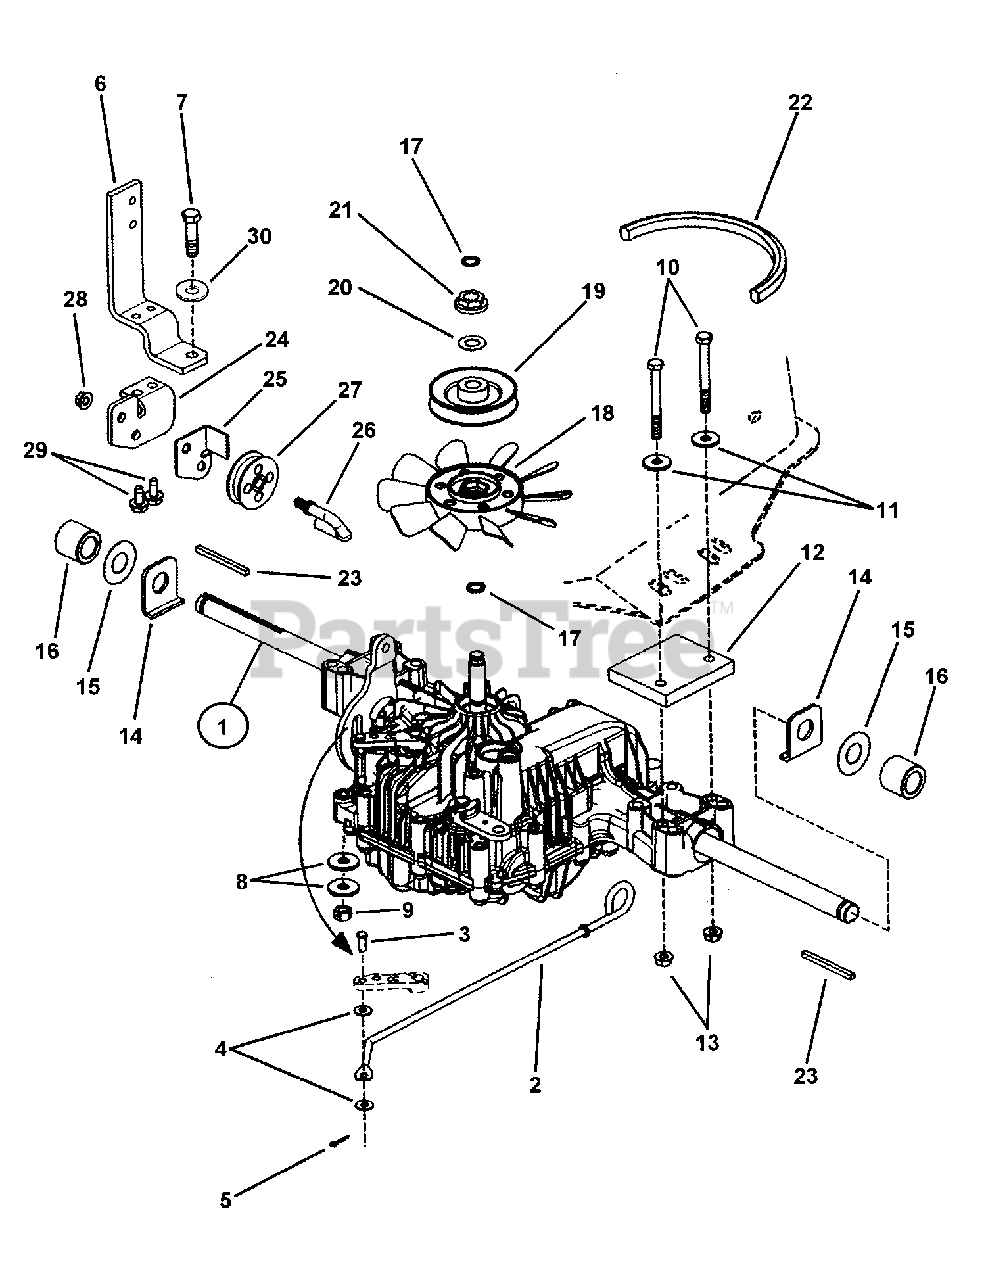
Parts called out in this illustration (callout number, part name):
1	ASSEMBLY, Transaxle-Tuff Torq, hand control K46 Hydro
2	ROD, Roll Release- K46
3	PIN, 1/4 x 5/8" Clevis
4	WASHER, 1/4 x 5/8 x 1/16" Flat
5	PIN, 3/32 x 1/2" Cotter
6	BRACKET, Torque/Spool- TTK46
7	SCREW, 5/16-18 x 2" Hex Head Cap, GR5
8	WASHER, 5/16 x 11/16 x 1/16" Flat, GR5
9	NUT, 5/16-18-3B Hex Nyloc
10	SCREW, 5/16-18 x 3" Hex Head Cap, GR5
11	WASHER, .34 x 1.0 x .09 Flat
12	SPACER, Hydro Axle- Steel- K46
13	NUT, 5/16-18 Hex Flange Lock, GR5
14	WASHER, Axle- TT K46 Hydro
15	THRUST WASHER
16	SPACER, Axle- K46
17	SNAP RING, Special (Kanzaki # 192154-89090) 1
18	FAN (Vendor # 1A640-83050)
19	PULLEY, 4" Diameter (Vendor # 1A6460-25333)
19A	PULLEY, C (Kanzaki P/N 1A6460-25333)
20	WASHER, Wave (Vendor # 1A6460-83060)
21	SPACER (Vendor # 1A6460-25300)
22	BELT, Traction Drive (HA Section, 97.881" Effective Length)
22	BELT, Traction Drive (HA Section, 96.60" Effective Length)
23	KEY, 3/16" Square x 2-3/16" long
24	BRACKET, Spool
25	GUIDE, Cable
26	ROD, Spool Pivot
27	SPOOL
28	NUT, 5/16-18 Hex Flange Lock, GR5
29	SCREW, 5/16-18 x 5/8" Hex Washer Self-Tap
30	WASHER, 5/16" Internal Tooth Lock
